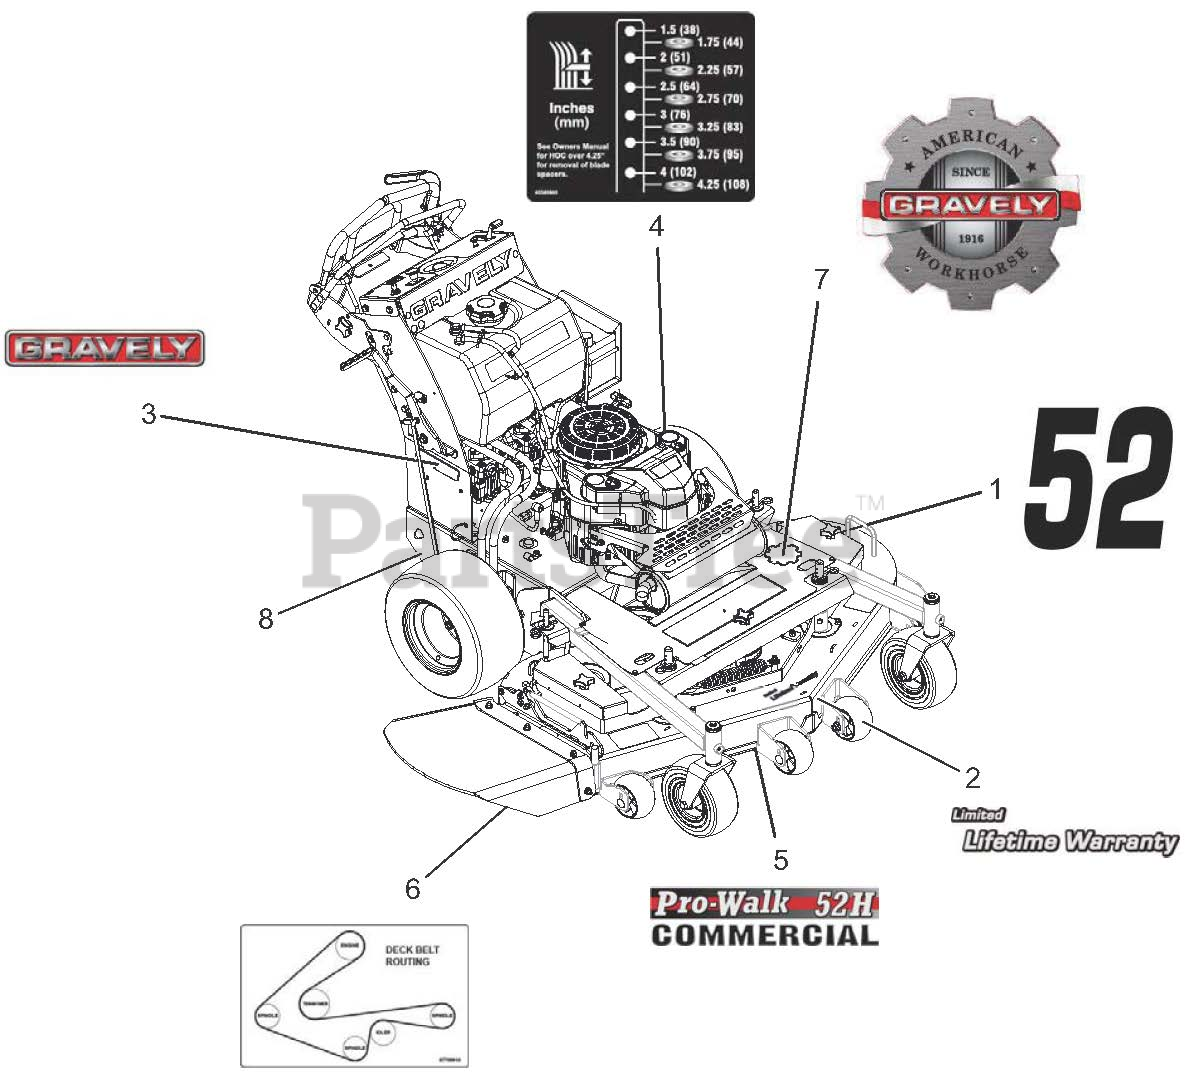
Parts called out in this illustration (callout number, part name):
1	DECAL, 52"
2	DECAL, LIMITED LIFETIME WARRANTY REV
3	DECAL, 6.5" GRAVELY LOGO
4	DECAL, PRO WALK HOC A
5	DECAL, PROWALK 52H
6	DECAL, BELT ROUTING 48/52 REV
7	DECAL, GRAVELY HERITAGE-LARGE
8	DECAL, PUMP BELT ROUTING
